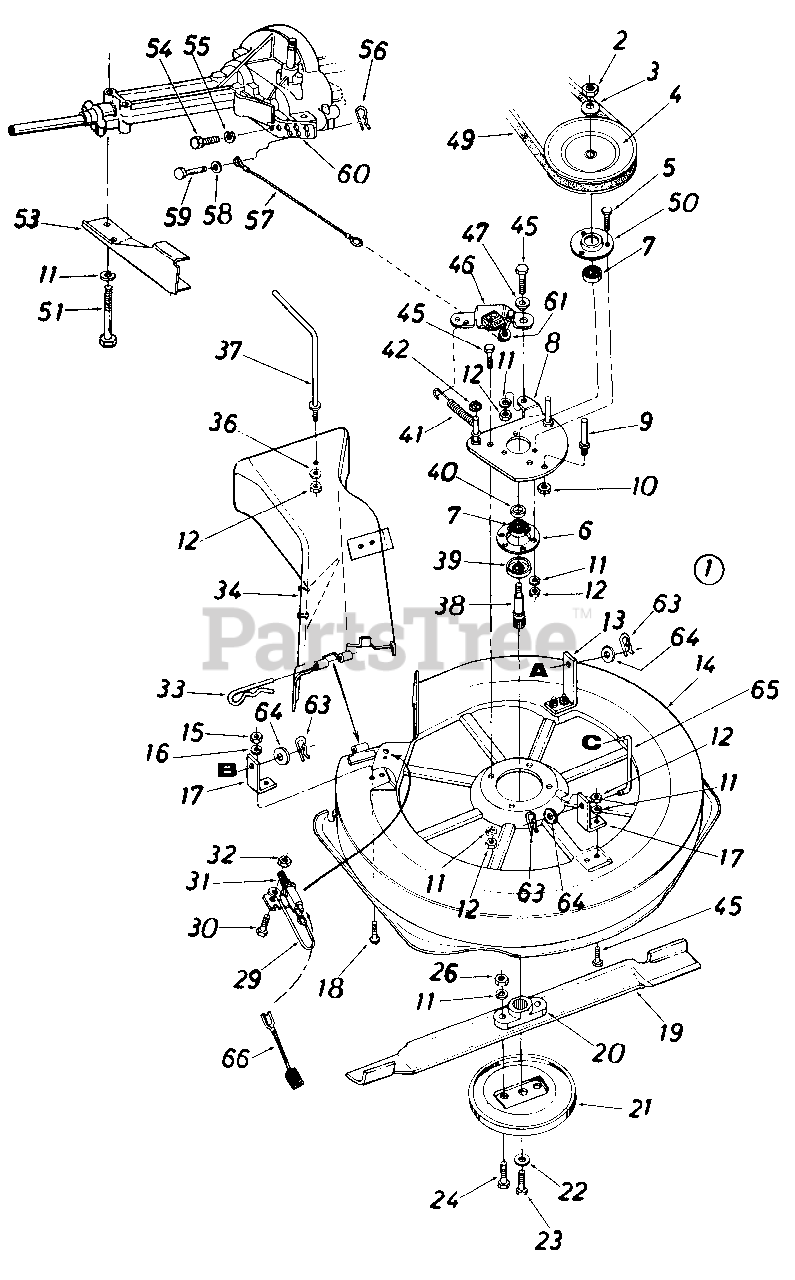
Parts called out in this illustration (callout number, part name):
1	30" R.D. Deck Ass'y. Comp.
2	Hex Jam Nut 5/8-18 Thd.
3	Bell-Wash. .630" I.D. x 1.25"
4	5/8 V-Pulley .75" I.D. x .7"
5	Hex Sems 5/16-18 x .62" Lg.
6	Brg. Housing 1.85" I.D.
7	Ball Brg. .787" I.D.
8	Spindle Mtg. Plate
9	Stud 3/8-16 x 2.75" Lg.
10	Hex Jam Nut 3/8-16 Thd.
11	L-Wash. 5/16" I.D.
12	Hex L-Nut 5/16-18 Thd.
13	Hanger Brkt. 2.92"
17	Hanger Brkt. 1.92"
18	Truss Mach. Scr. 5/16-18 x .75" Lg.
19	30" High Lift Blade
20	Blade Adapter
21	Scalp Plate
22	L-Wash. 3/8" I.D.
23	Hex Bolt 3/8-24 x 1.0"
24	Hex Bolt 5/16-24 x 1.0" Lg.
26	Hex Nut 5/16-24 Thd.
29	Electrical Wire
30	Hex Bolt 1/4-20 x 50" Lg.
31	Safety Switch
32	Hex Nut 1/4-20 Thd.
33	Internal Cotter Pin
34	R.D. Chute Deflector
36	L-Wash. .32" I.D. x .62" O.D.
37	90ø Rod 5/16-18 Thd.
38	Blade Spindle 5.20
39	Bearing Shield
40	Spacer
41	Extension Spring
42	Push Speed Nut
45	Hex Bolt 5/16-18 x .75
46	Blade Brake Brkt. Ass'y.
47	Shoulder Spacer .500" Dia.
49	"V"-Belt 1/2" x 52" Lg .
50	Open Brg. Housing
51	Hex Bolt 5/16-18 x 2.75"
53	Lower Outside Belt Guard
54	Hex Bolt 1/4-20 x .62" Lg.
55	L-Wash. 1/4" I.D.
56	Int. Cot. Pin 5/16" Dia.
57	Brake Cable 11.75" Lg.
58	Fl-Wash. .281" I.D. x 50
59	Clevis Pin 1/4" Dia.
60	Lower Inside Belt Guard
61	Cap Speed Nut 1/4" Rod
63	Int. Cotter Pin 1/2" Dia.
64	Fl-Wash. 531" I.D. x 930"
65	Deck Link 3.9" Lg.
66	Wire Lead
